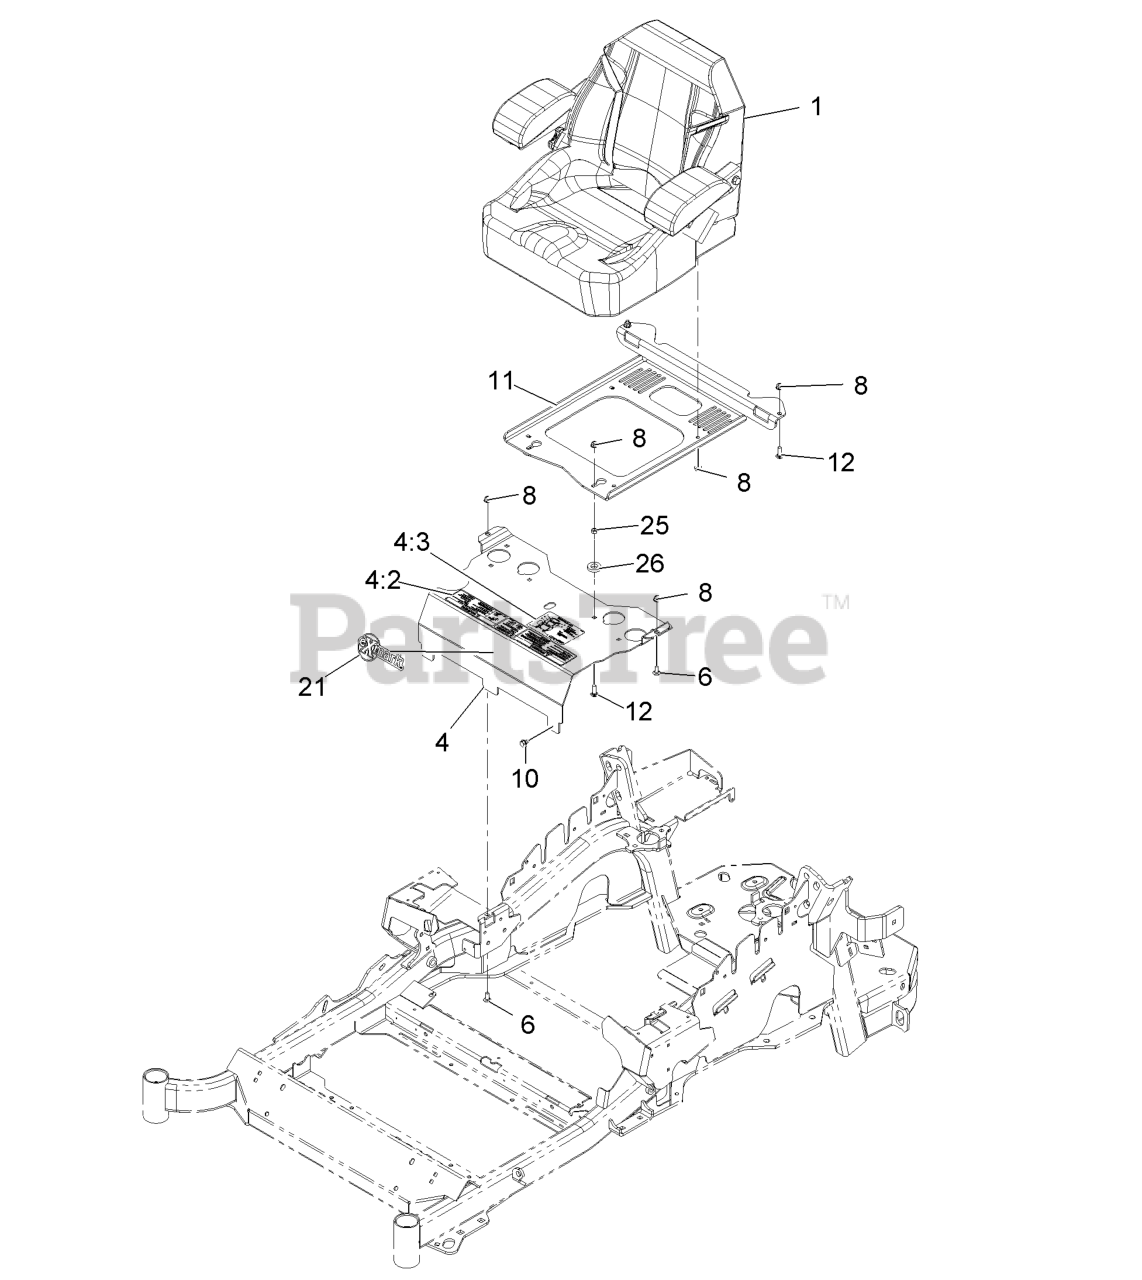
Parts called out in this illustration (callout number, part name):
4	MOUNT-SEAT
4:2	DECAL-CONSOLE
4:3	DECAL-SERVICE AID
6	SCREW-CARR
8	NUT-HF, NI
11	PLATE-SUPPORT, SEAT
12	SCREW-CARR
25	NUT-HEX
